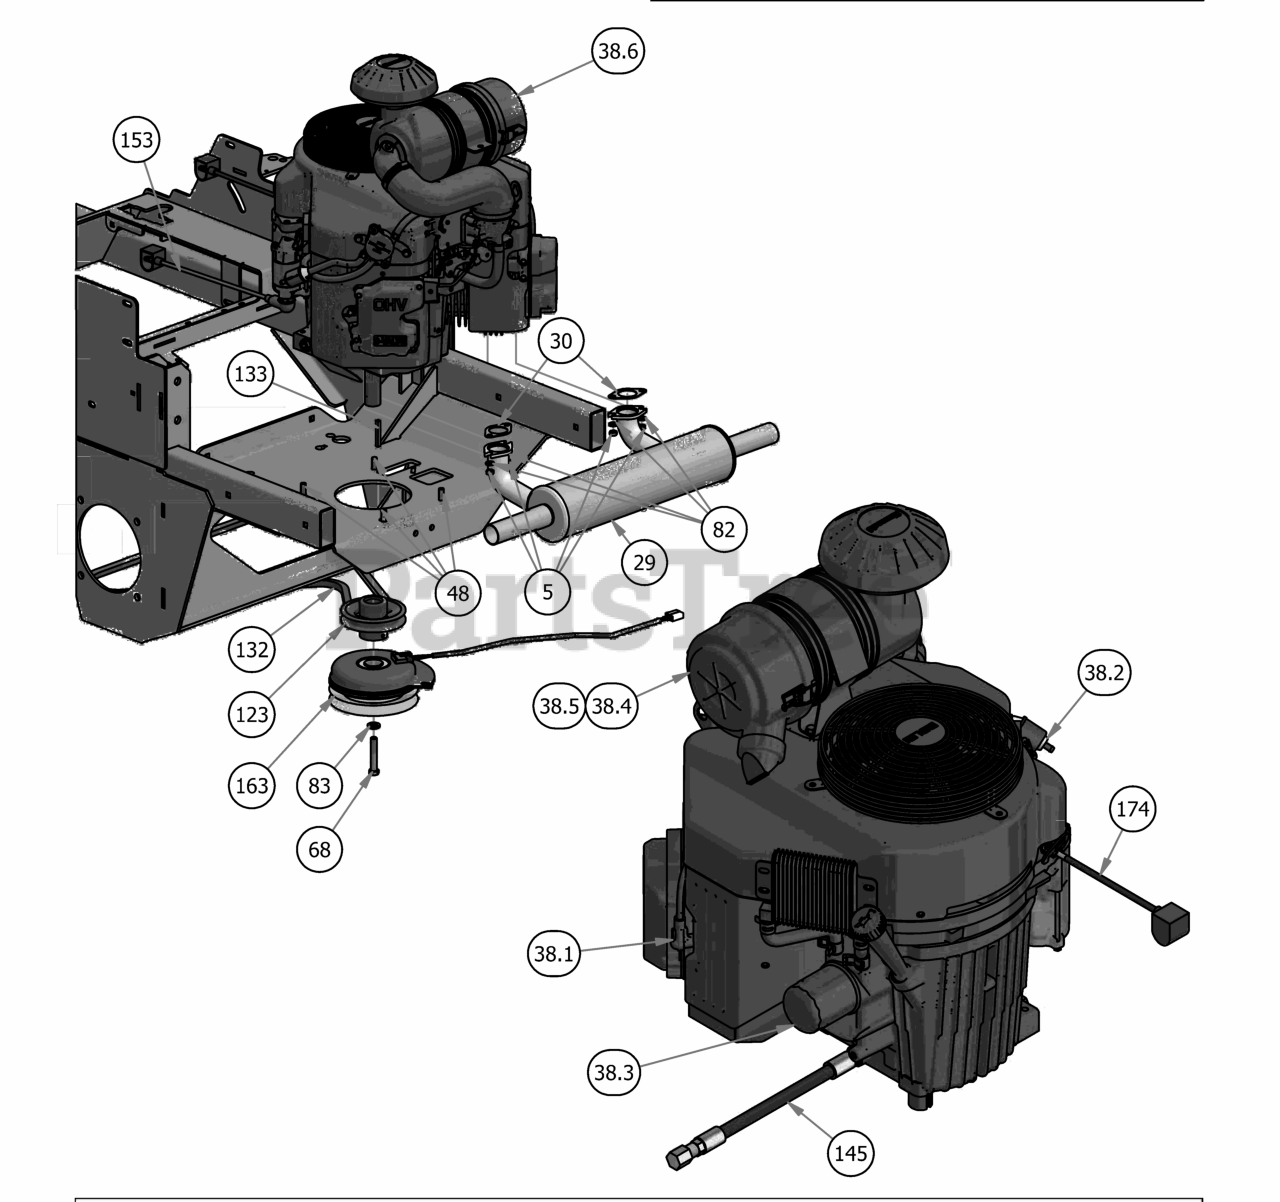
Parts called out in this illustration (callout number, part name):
5	M8-1.25 Zinc Nut
29	Muffler for Kawasaki FX1000
30	Exhaust Gasket
38.1	Spark Plug - Kawasaki
38.2	Universal Inline Fuel Filter
38.3	Oil Filter
38.4	Canister Air Filter- Outer
38.5	Canister Air Filter- Inner
39	Kawasaki FX1000 Engine
48	3/8 x 1 1/8 bolt
68	7/16" x 2 1/2" Hex Bolt
82	5/16" Lock Washer
83	7/16" Lock Washer
123	4 3/4 Motor Pulley
132	2019 Rebel Pump Belt
133	1/4 x 2 Square key Stock
145	Kawasaki Oil Drain
153	14" Red Battery Cable-Base Outlaw
163	Clutch Assembly
164	Clutch Pigtail
165	2019 Rigid Frame
174	Starter Cable
